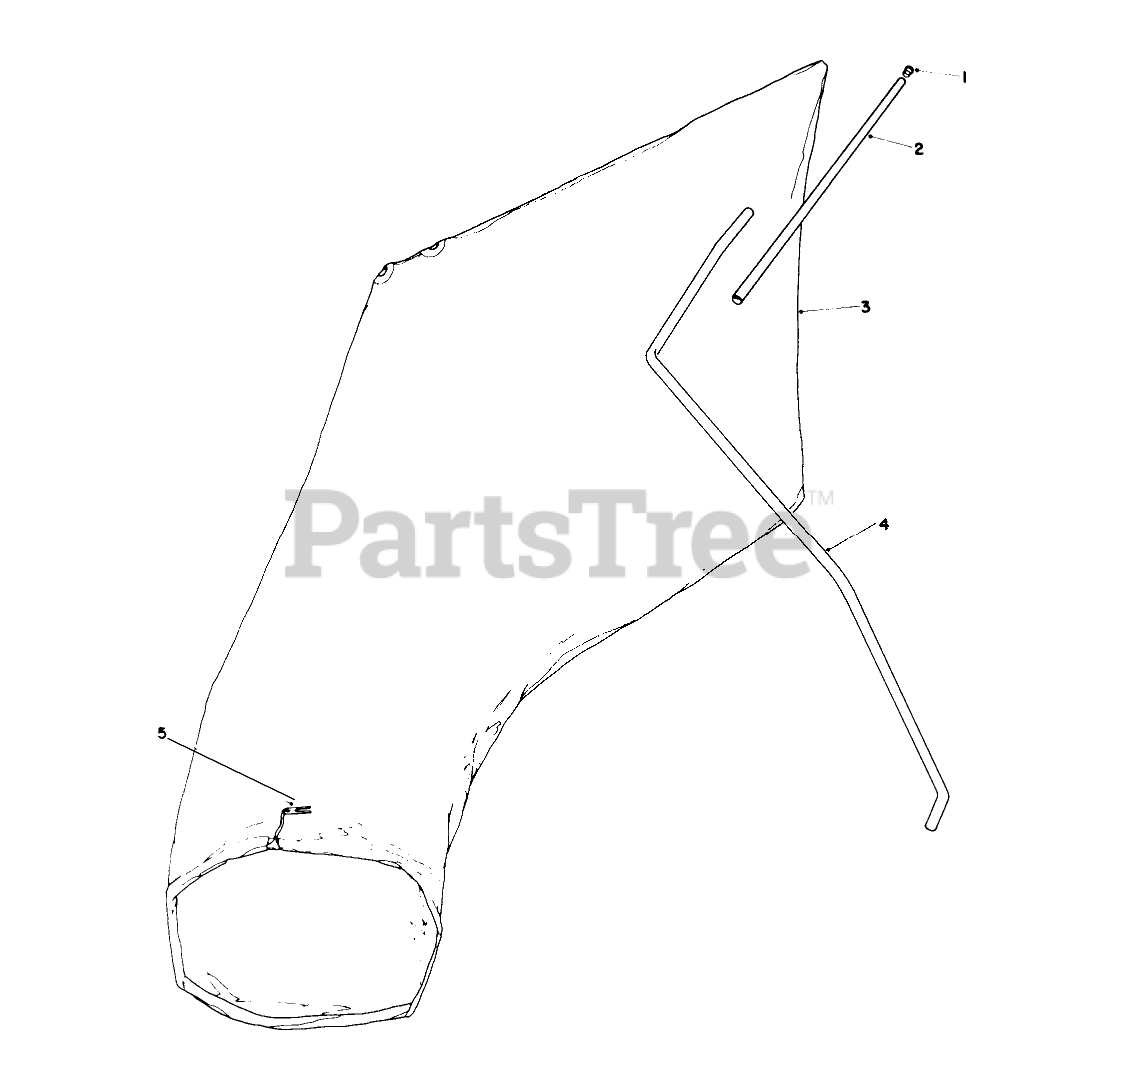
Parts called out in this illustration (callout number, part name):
2	BAG HANGER TUBE
3	Bag (Incl. Ref. #5)
4	HANGER ROD
5	BAG CORD FASTENER
